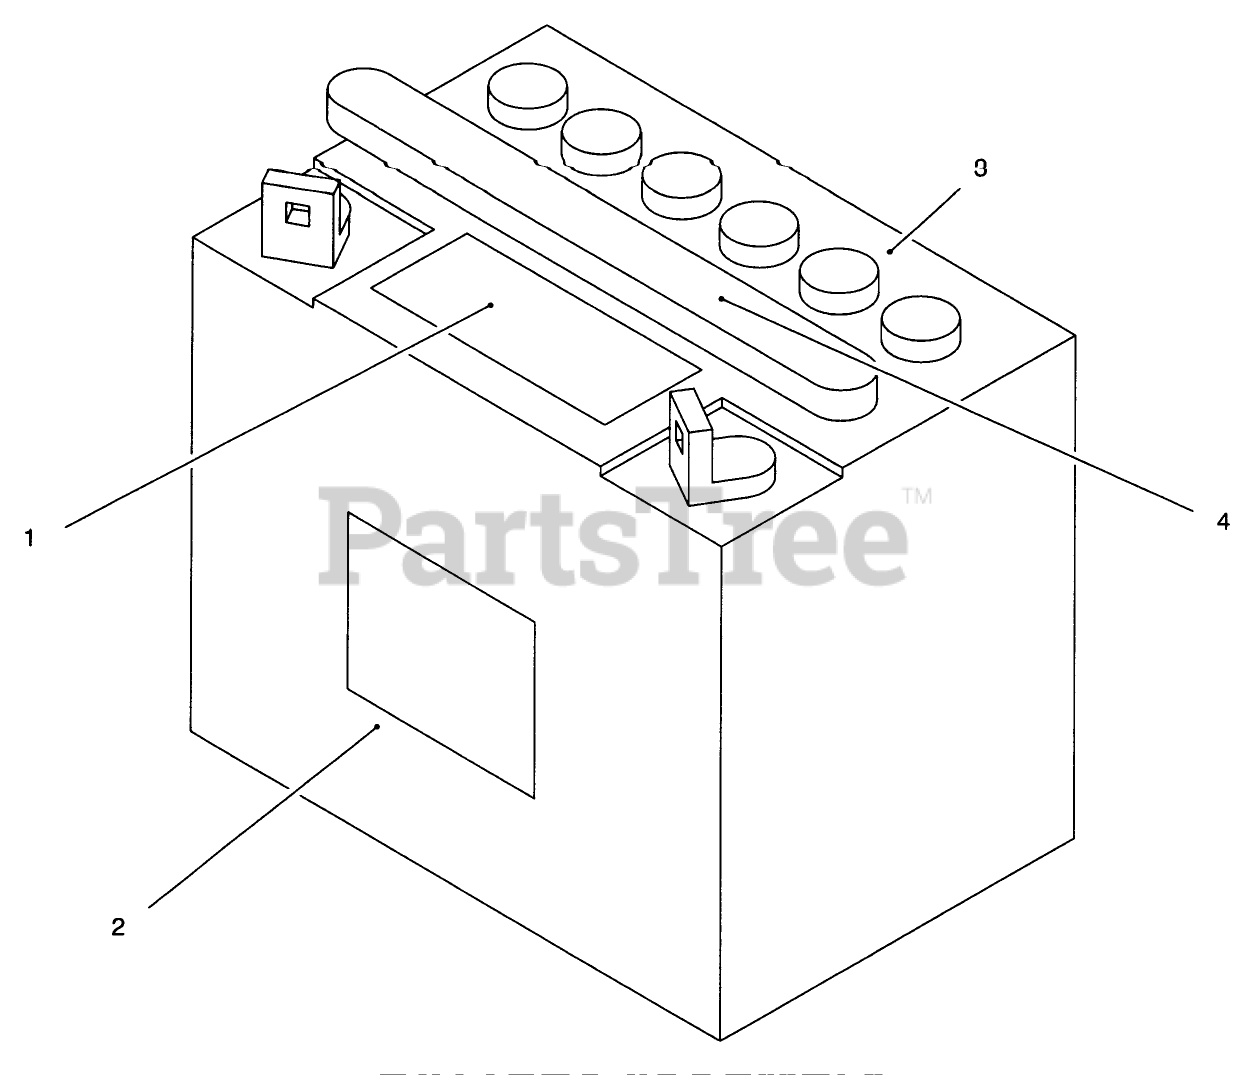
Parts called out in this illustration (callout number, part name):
1	DECAL-DANGER
2	DECAL-BATTERY
3	CAP-BATTERY
4	DECAL - DANGER
